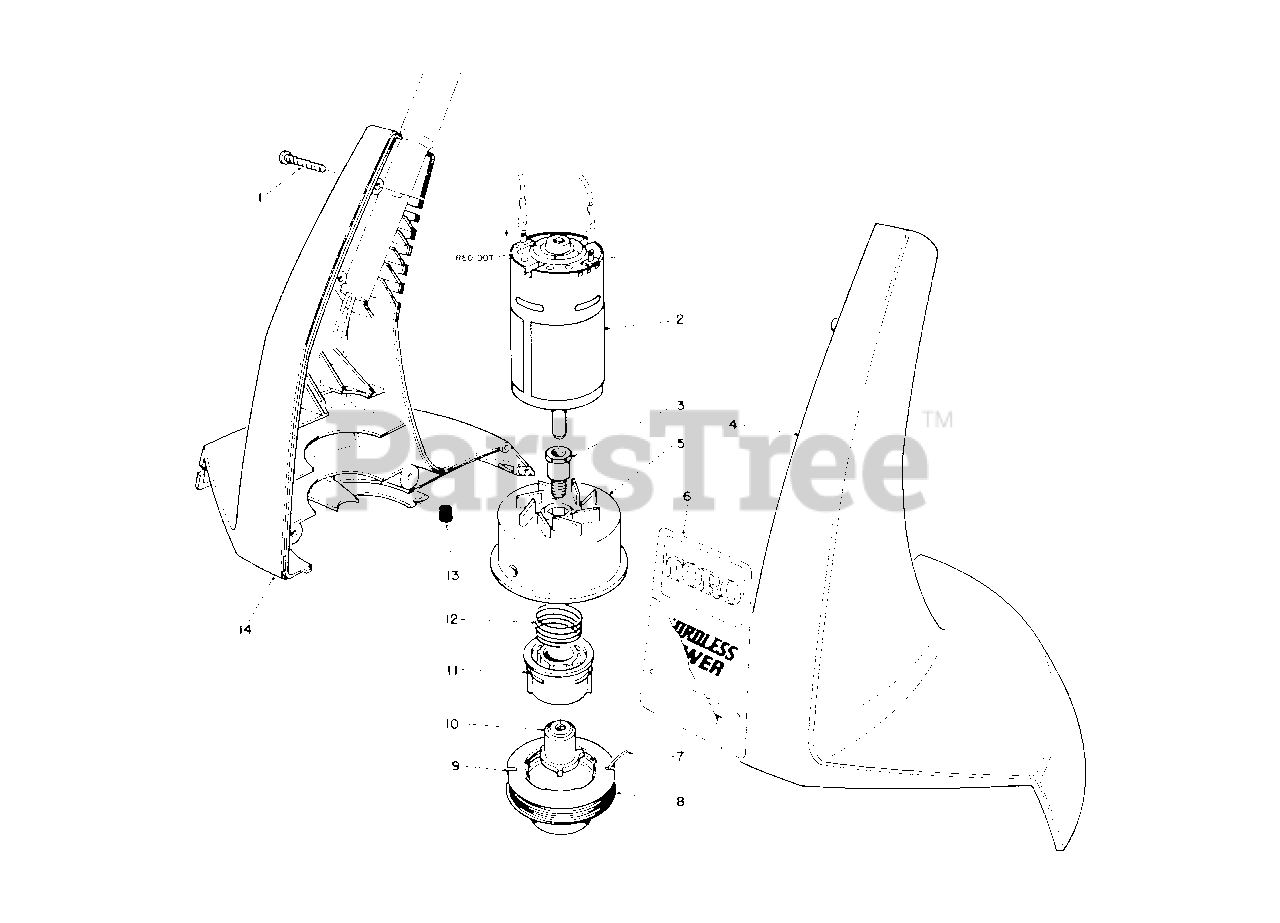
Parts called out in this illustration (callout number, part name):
1	Screw-Thread Forming
2	Motor Assembly (Incl. Ref. #3)
3	Extension-Shaft
4	Housing-L.H.
5	Drum-Assembly
8	Pre-wound Spool (Incl. Ref. #7 & 9)
9	Spool-Cup
11	Core-Spool
12	Spring-Compression
14	Housing-R.H.
